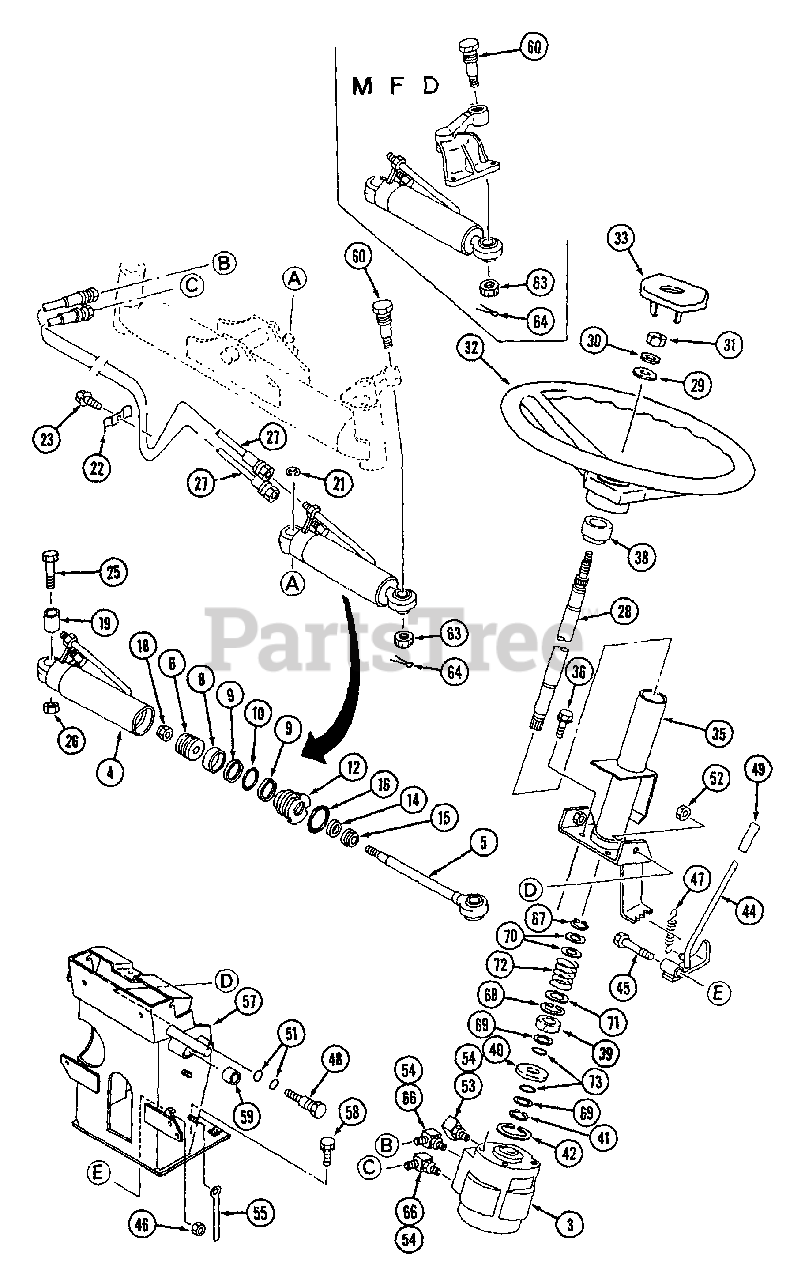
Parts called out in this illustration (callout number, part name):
3	Steering Unit
25	Bolt
26	Nut
28	Shaft, Steering
32	Steering Wheel
36	Bolt w/Washer
38	Bushing, Column
53	Valve, Check
57	Bracket, Column
58	Bolt w/Washer
66	Elbow
